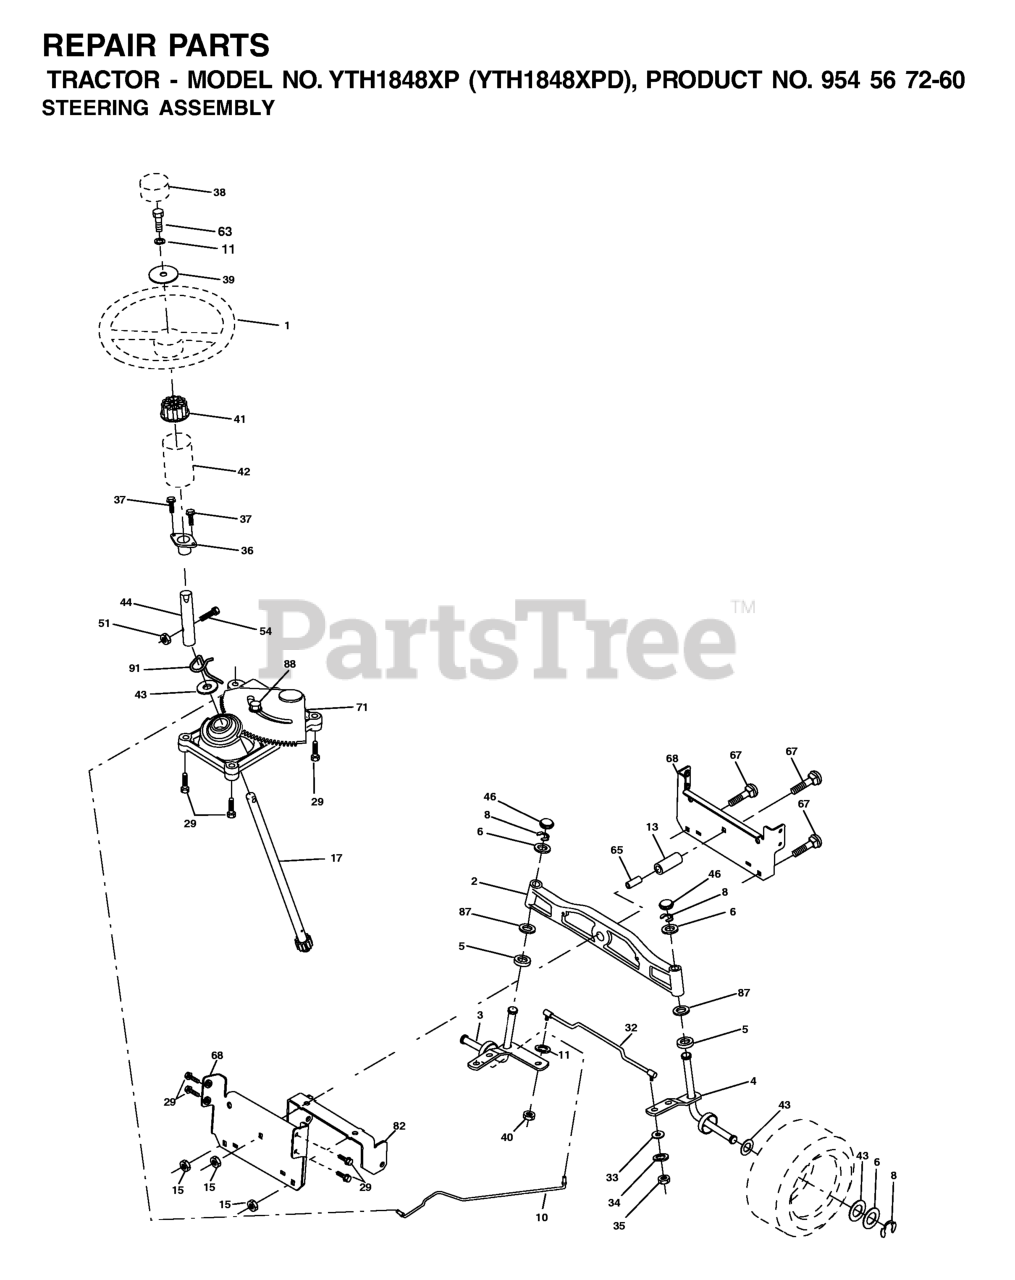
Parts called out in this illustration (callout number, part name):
1	STEERING WHEEL
2	AXLE ASM
3	SPINDLE.ASM.LH.15"TIRES
4	SPINDLE.ASM.RH.15"TIRES
5	THRUST WASHER
10	DRAGLINK.15".TIRES.2001
11	WASHER, LOCK 3/8
13	TUBE, PIVOT AXLE
15	NUT
17	SHAFT ASM
29	SCREW 3/8-16X3/4
32	ROD.ASM.TIE.BALL.JOINT.NOVAN
33	WASHER M
34	WASHER.LOCK.HVY.HLCL.SPR.5/16
35	NUT, CROWNLOCK
36	BUSHING, STEERING
37	SCREW.TT.#10-32X.5.3/8.FLANGE
38	CAP.WHEEL.STEERING.GREY
39	Washer 13/32 x 1-1/20 x 11 Gauge
40	GRIPCO NUT
41	STEERING WHEEL ADAPTOR
42	BOOT STEERING
44	EXT SHAFT STEERING
46	CAP.SPINDLE.BLACK
51	NUT.71038.31-18.HEX.NYLOCK
54	BOLT.5/16-18X1-1/4 FULL.THREAD
65	SPACER BRACE AXLE
67	BOLT
68	BRACE.AXLE.15"TIRES
71	STEERING ASM
82	BRACKET
87	WASHER, FLAT .781 X 1 1/2"
88	BOLT, SHOULDER 7/16-20
91	CLIP.STEERING
